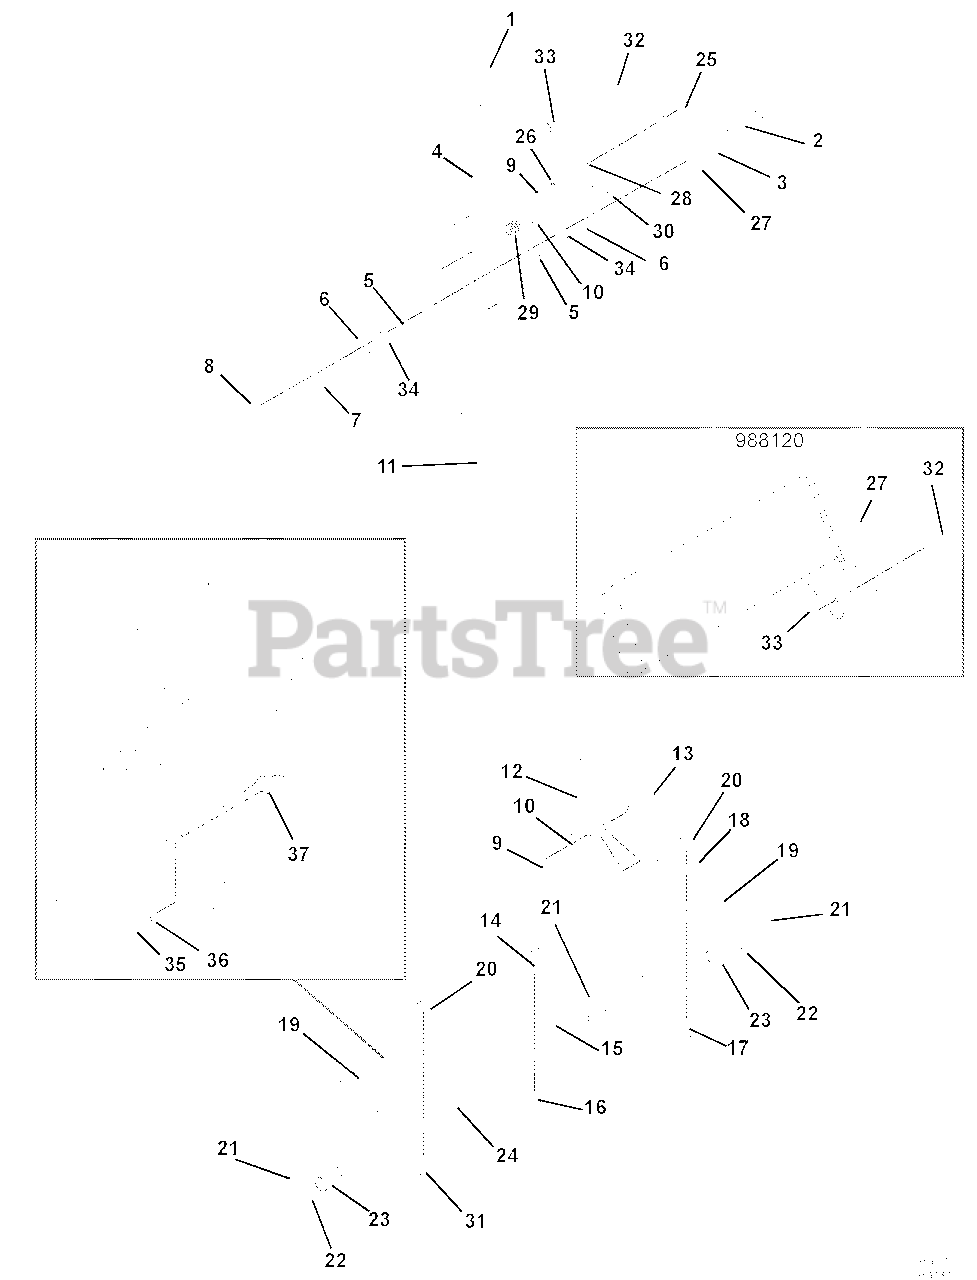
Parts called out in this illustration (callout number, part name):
1	Knob, Ball-Black 1-.41, .375-1
2	Bolt-Hex .44-14 x 4.5 Grade 5
3	Washer-Flat-Steel .50 x 1.25 x .083
4	Weldment- Handle
5	Washer-Flat-Nylon .76 x 1.25 x .030
6	Washer-Flat-Steel .76 x 1.38 x .062
7	Pivot, Brake
8	Nut-Locking-Hex .44-14
9	Pin-Hair Internal .08 x .18 x 1.18
10	Washer-Flat-Steel .406 x .812 x .065
11	Rod, Brake (105, 108, 123, 126)
12	Clevis,.38-24 Adjustable
13	Pin-Clevis .37 x 1.75
14	Bolt-Hex .38-16 x 1.00 Grade 5
15	Bracket, Brake Shaft
16	Nut-Locking-Nylon .38-16
17	Bolt-Hex .25-20 x 1.50 Grade 5
18	Brake, Arm
19	Pad, Brake
20	Nut-Locking-Nylon .25-20
21	Pin-Cotter .12 x 1.00
22	Washer-Flat-Steel .656 x 1.31 x .095
23	Bushing-Flange .63 x 1.00 x .625 Nylon
24	Brake, Shaft
25	Screw-Machine 10-24 x .75 Hex Washer Head
26	Nut-Locking-Nylon 10-24 with Insert
27	Bracket, Parking Brake Switch (105, 108, 123, 126)
28	Switch, Interlock
29	Spring-Compression .045 x .60 x .75
30	Boot, Rubber
31	Bolt-Hex .25-20 x 1.25 Grade 5
32	Bolt-Serrated Hex Flange Washer Head .25-20 x .75 (105, 108, 123, 126)
33	Nut-Locking-Top-Flange .25-20 (105, 108, 123, 126)
34	Washer-Wave .076 x 1.12 x .080
35	Bolt-Hex .38-16 x 1.75 Grade 5
36	Nut-Hex .38-16
37	Nut-Locking-Nylon .38-16
